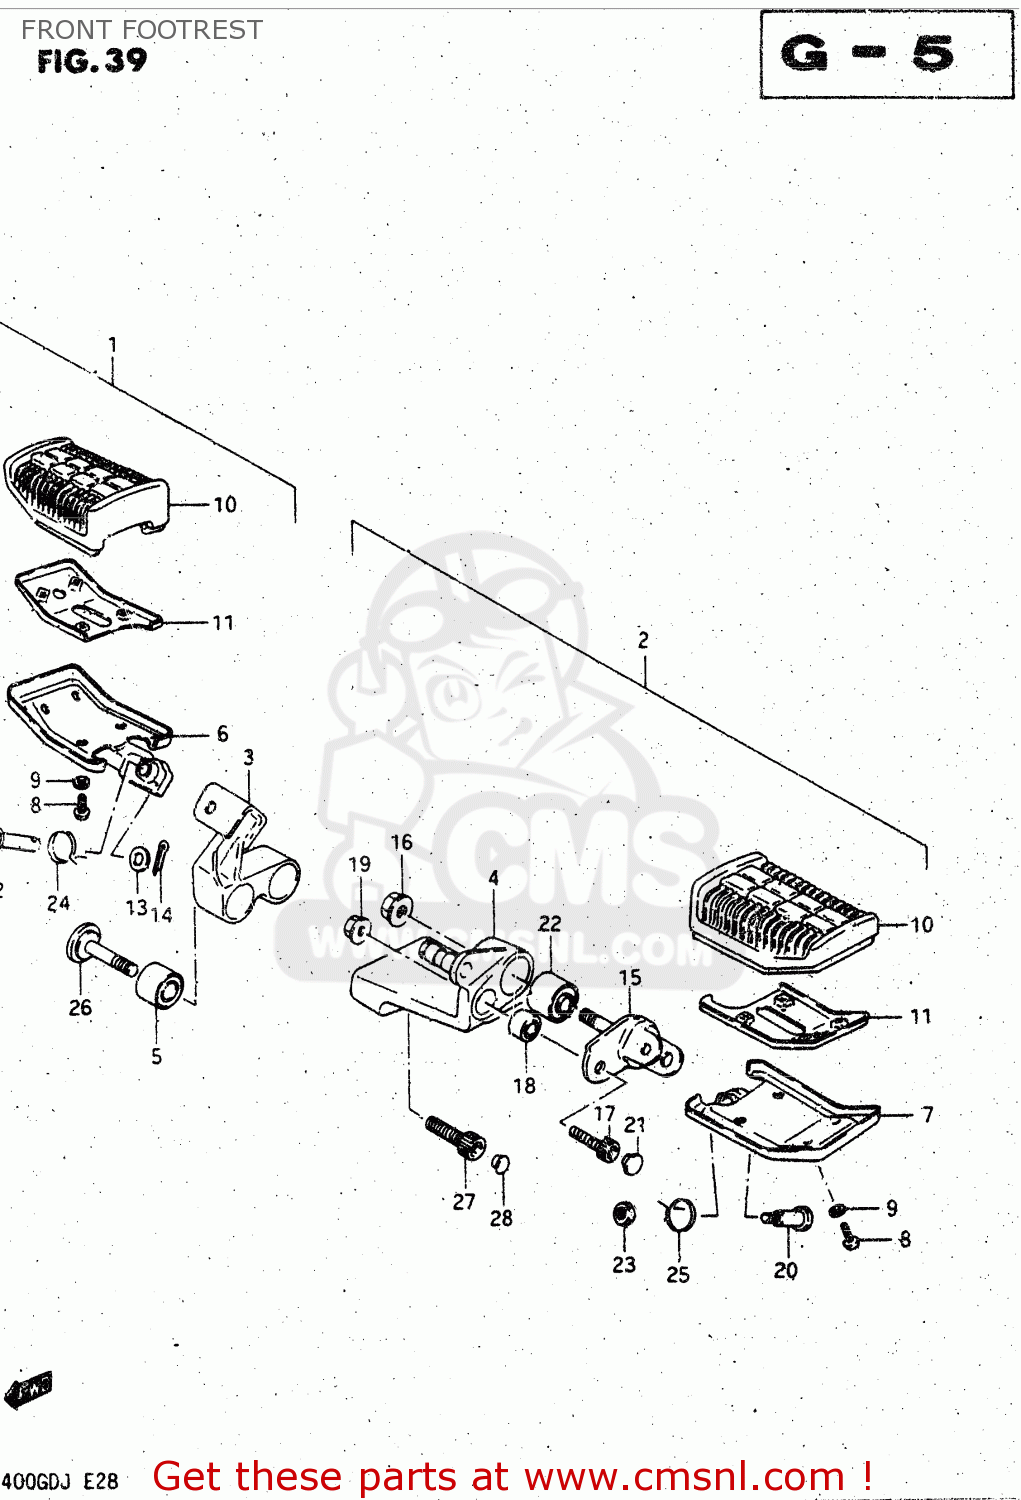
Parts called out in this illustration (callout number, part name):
1	FOOTREST ASSEMBLY,FRONT,RIGHT
2	FOOTREST ASSEMBLY,FRONT,LEFT
3	BAR COMP,FRONT FOOTREST
4	BAR COMP,FRONT FOOTREST
5	BUSHING
6	HOLDER COMP,FRONT FOOT
7	HOLDER COMP,FRONT FOOT
8	SCREW
9	LOCK WASHER
10	RUBBER,FR FOOTREST
11	PLATE,FOOTREST RUBBER
12	PIN
13	WASHER
14	PIN 20X20
15	BOSS COMP,FOOTREST HOLDER
16	NUT
17	BOLT
18	BUSH
19	NUT
20	BOLT
21	CAP(OD:14.5)
22	BUSHING
23	NUT 6MM
24	SPRING
25	SPRING
26	BOLT 10X51
27	BOLT, LH
28	CAP
